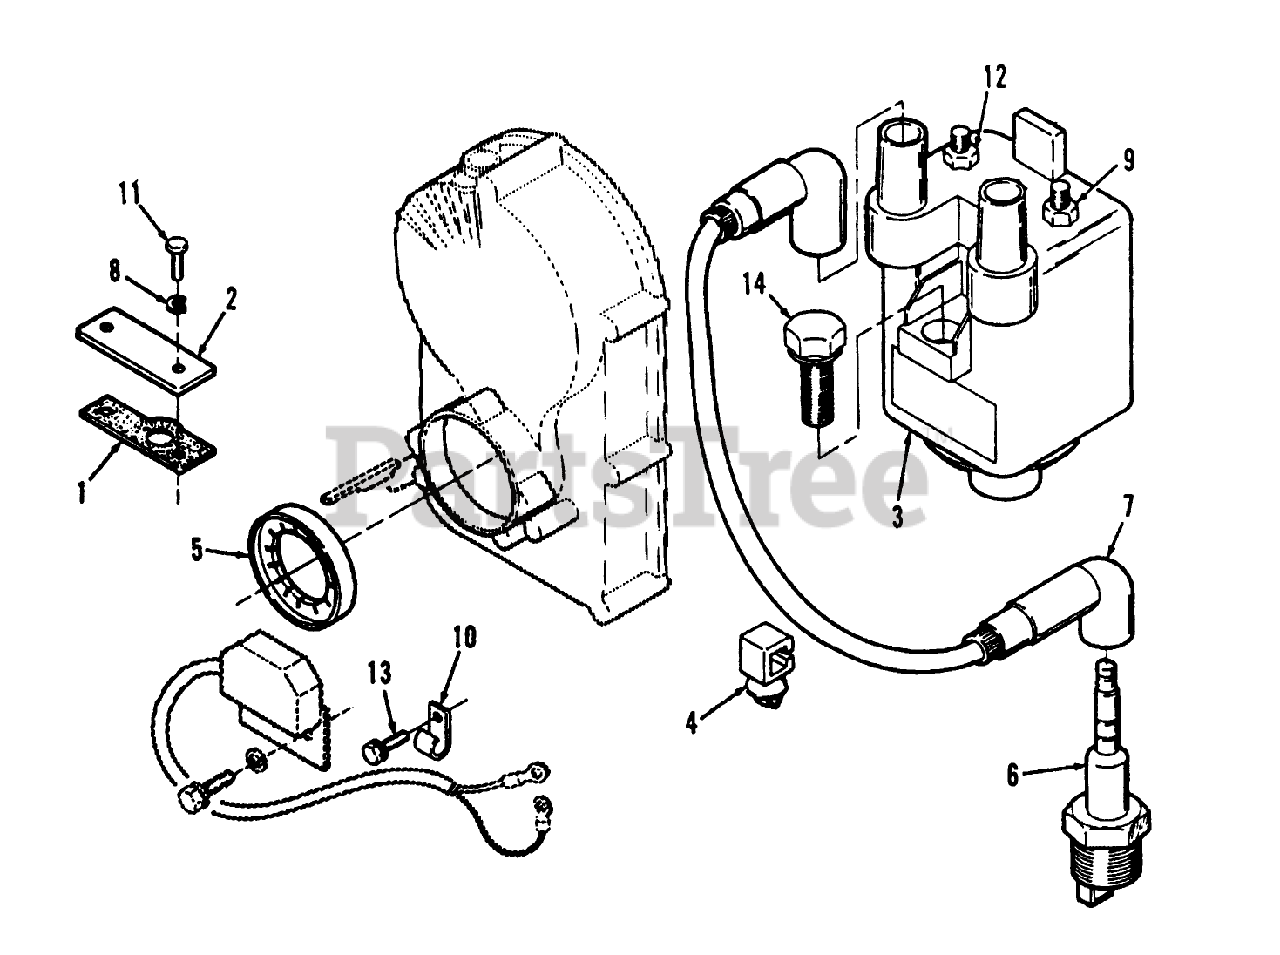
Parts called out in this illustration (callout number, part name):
8	WASHER-FLAT
11	SCREW - CAP HEX HEAD
14	0 Screw-Hex Washer Hd
